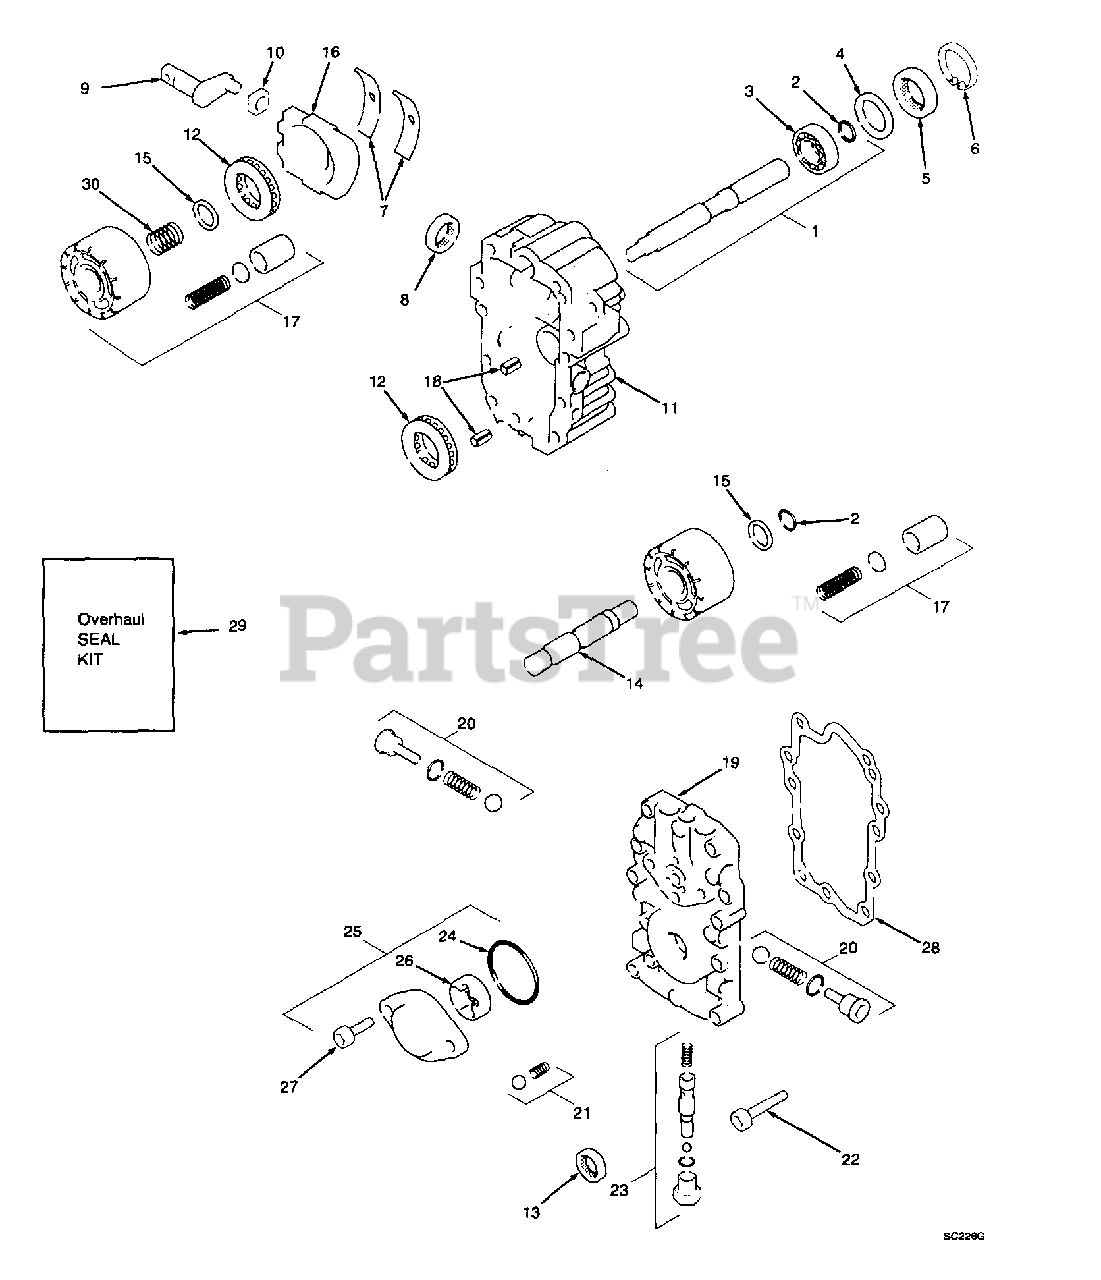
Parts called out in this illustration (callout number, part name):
1	Pump Shaft Kit
2	Wire Retaining Ring
3	Ball Bearing
5	Lip Seal (16 x 35 x 7)
6	Retaining Ring
7	Cradle Bearing
8	Lip Seal (12 x 35 x 7)
9	Trunnion Arm
10	Slot Guide
11	Transmission Housing Kit RH
12	Thrust Ball Bearing Assembly
13	Lip Seal (15 x 24 x 7)
14	Motor Shaft
15	Block Thrust Washer
16	Variable Swath Plate
17	BDP-10L Block Assembly
18	Pin ST Holder
19	Center Section Kit
20	Check Valve Kit
21	Charge Relief Kit
22	Socket Head Cap Screw
23	Bypass Valve Kit
25	Charge Pump Cover
26	Gerotor Assembly
27	Capscrew (6mm x 20")
28	Center Section Gasket
29	Overhaul Seal Kit
30	Spring Block
